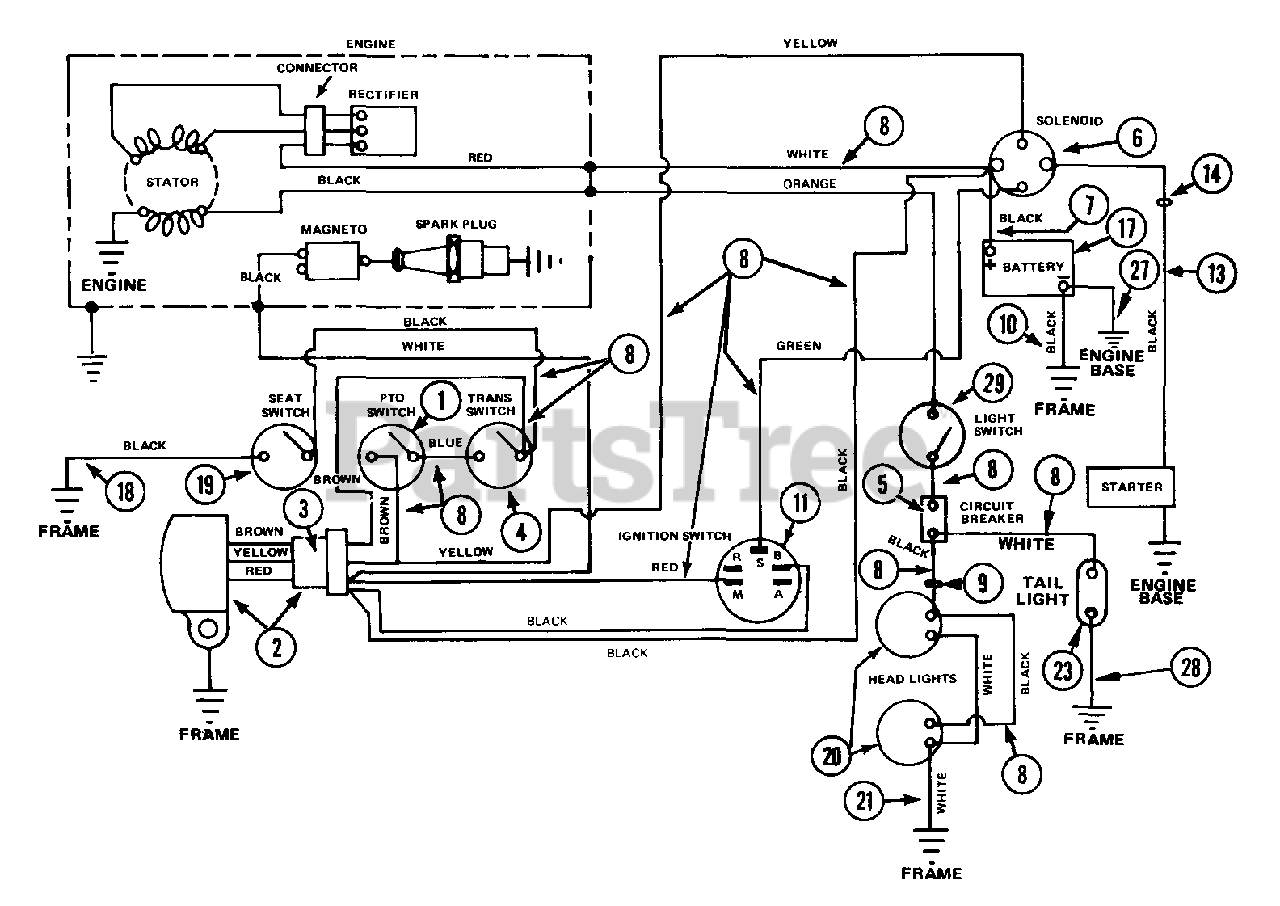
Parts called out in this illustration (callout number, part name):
1	SWITCH INTERLOCK
2	MODULE
3	CONNECTOR
4	SWITCH-NEUTRAL START N.O.
5	CIRCUIT BREAKER
6	SOLENOID
7	GROUND CABLE
8	WIRE HARNESS
9	CLAMP LOOP
10	GROUND CABLE
11	IGNITION SWITCH AND KEY ASSEMB
12	LIGHT SWITCH
13	GROUND CABLE
14	TIE DOWN
15	CABLE RETAINER
17	BATTERY
18	GROUND WIRE
19	SWITCH SEAT
20	HEAD LIGHT
22	TAIL LIGHT WIRE
23	TAIL LIGHT
27	GROUND CABLE .31X22.00X.31
28	GROUND WIRE
